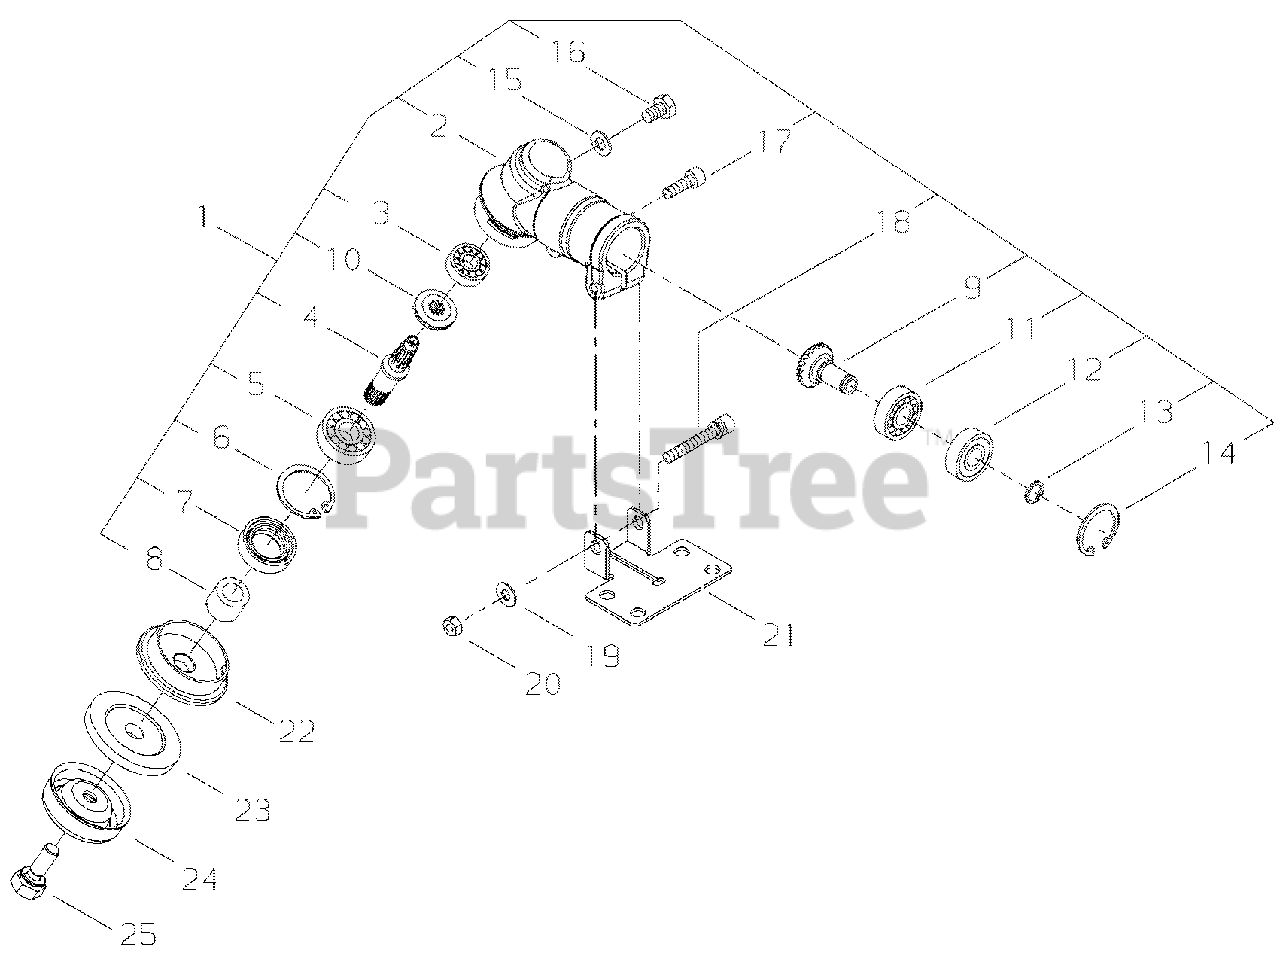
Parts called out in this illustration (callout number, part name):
1	GEAR CASE ASSY
2	CASE, GEAR
3	BEARING, BALL - 626MOS
4	GEAR - SHAFT
5	BEARING, BALL - 6000MOS
6	RING, RETAINING - 26
7	SEAL, OIL
8	COLLAR
9	GEAR - SHAFT
10	GEAR - BEVEL
11	BEARING, BALL - 609 MOS
12	BEARING, BALL - 609Z MOS
13	RING, RETAINING - 9
14	RING, RETAINING - 24
15	WASHER - 6
16	BOLT - 6X10
17	SCREW - 5X10
18	SCREW - 5X40
19	WASHER - 5
21	MOUNTING PLATE, SHIELD
22	HOLDER - A
23	CLIP
24	GUARD
25	SCREW - 7X20
